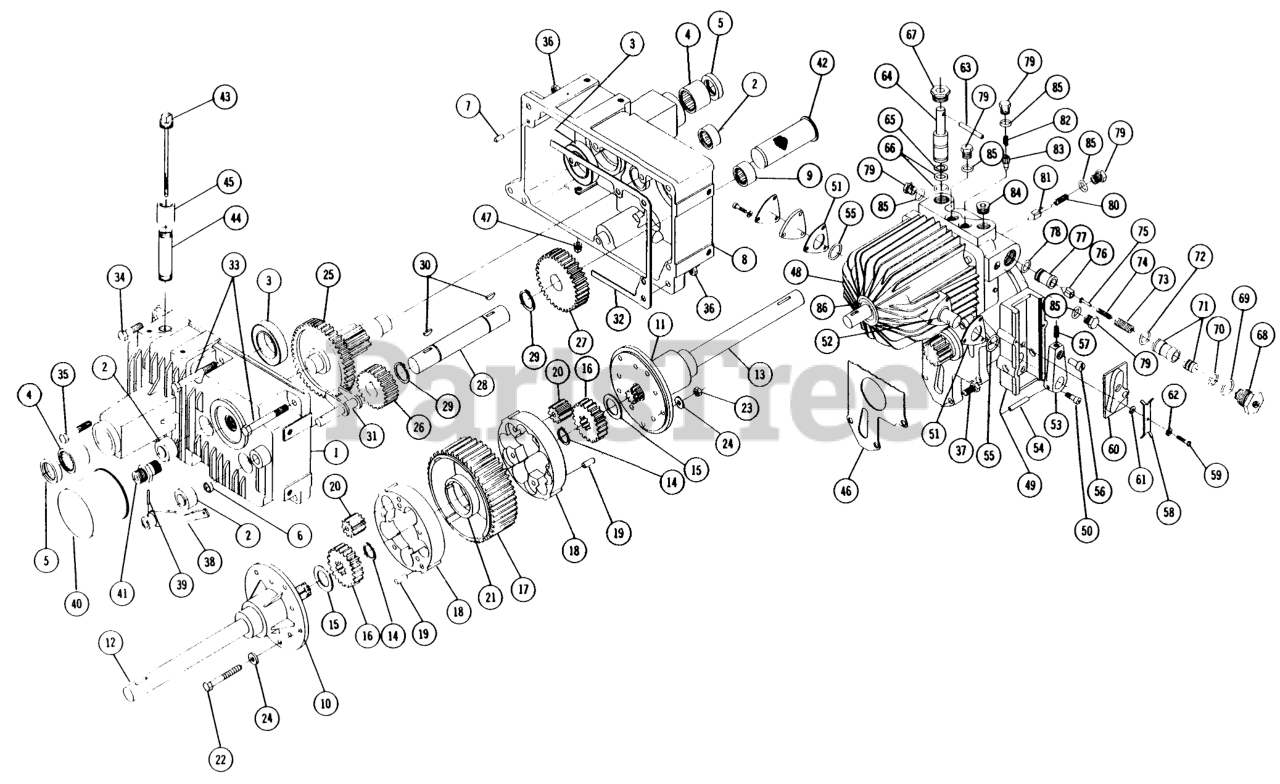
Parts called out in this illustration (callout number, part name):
2	BEARING-NEEDLE
5	SEAL-OIL
7	PIN-DOWEL
18	BULLT 252
22	Bolt Hex 3 1/4
23	3/8-16 E.S.
24	Washer
30	Key
33	Bolt Hex 3/8-16 x 5
34	Bolt, 3/8 16 x 2
35	Bolt Hex 3/8-16 x 1
37	Bolt, 3/8-16 x 1
41	FITTING
44	Nipple 1/2 Pipe x 31/2
45	Coupling 1/2 Pipe
48	SRV BULLT 437B
53	Arm-Cam Follower
54	ROLL PIN 1/4 X 1-1/4
57	Set Screw-1/4-20 x 1/2
59	Bolt-Rd. Heed #8-32 x 1/2
60	CAM
61	Washer
62	Lockwasher
63	SPIROL PIN
66	O Ring
70	O RING
72	O RING
80	SPRING-SUNDSTRAND
82	Spring Charge Pump Valve
85	O RING
